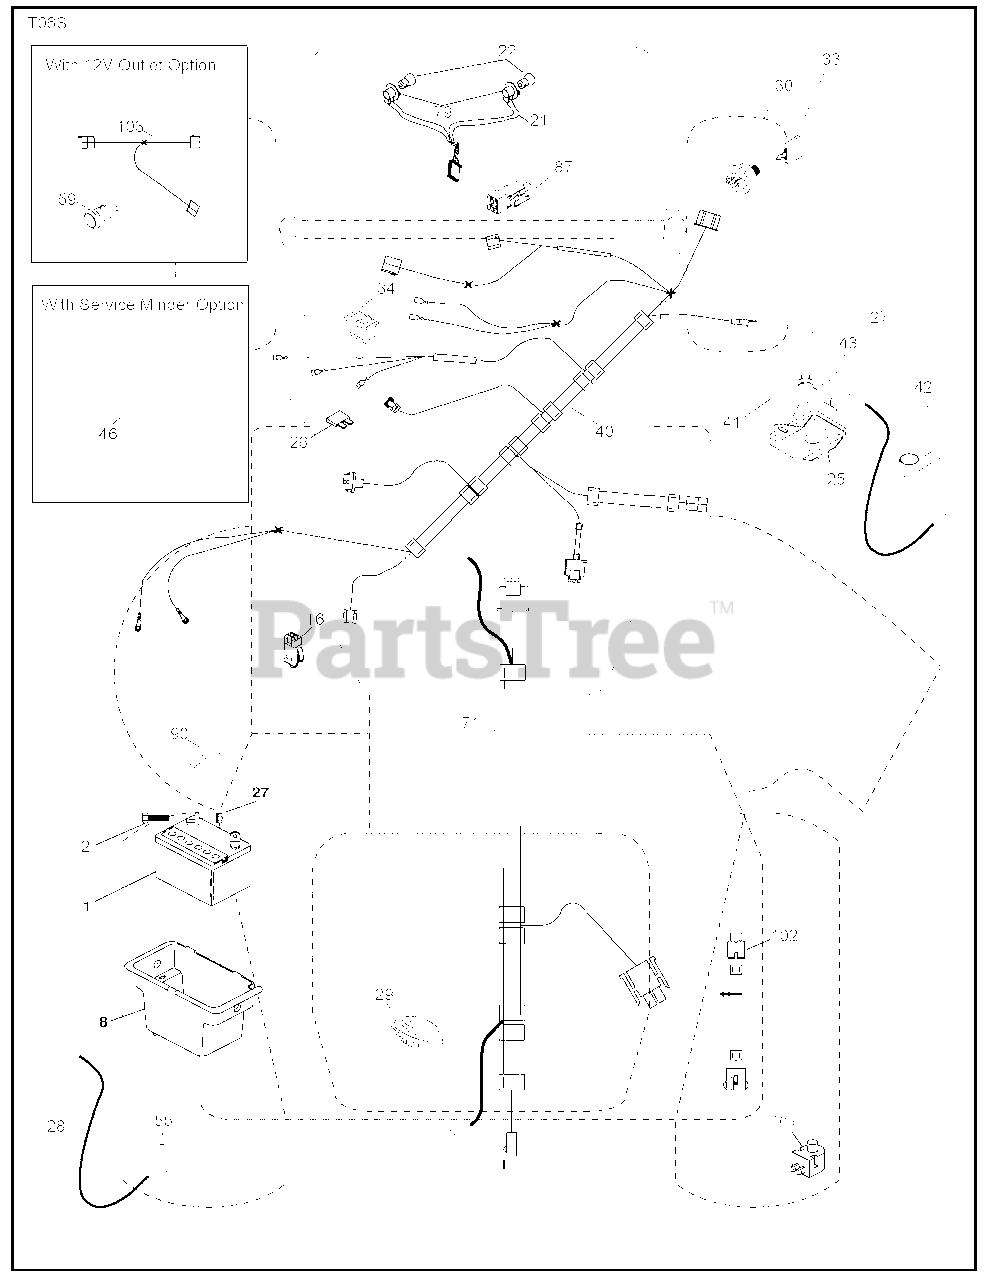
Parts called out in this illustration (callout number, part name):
1	Battery
2	Bolt Hex Head 1/4-20 x 3/4
8	Box Battery
16	Switch Interlock Push-In
21	Harness Socket Light w/4152J
22	Bulb Light
25	Cable Starter
27	Nut Keps Hex 1/4-20 unc
28	Cable, Ground
29	Switch, Seat
30	Switch, Ign
33	Key/Chain
34	Switch Light/Reset
40	Harness Ign. Dash
41	Screw Thd Cut 1/4-20 x 1/2
42	Cover, Terminal
43	Solenoid
46	Gauge Serviceminder Hrmtr
55	Screw Thdrol 5/16-18 x 3/4 TYTT
71	Harness Ign.
79	Socket Asm. Bulb
87	Switch Interlock
90	Cover Terminal
102	Harness Pigtail
105	Switch Reverse
